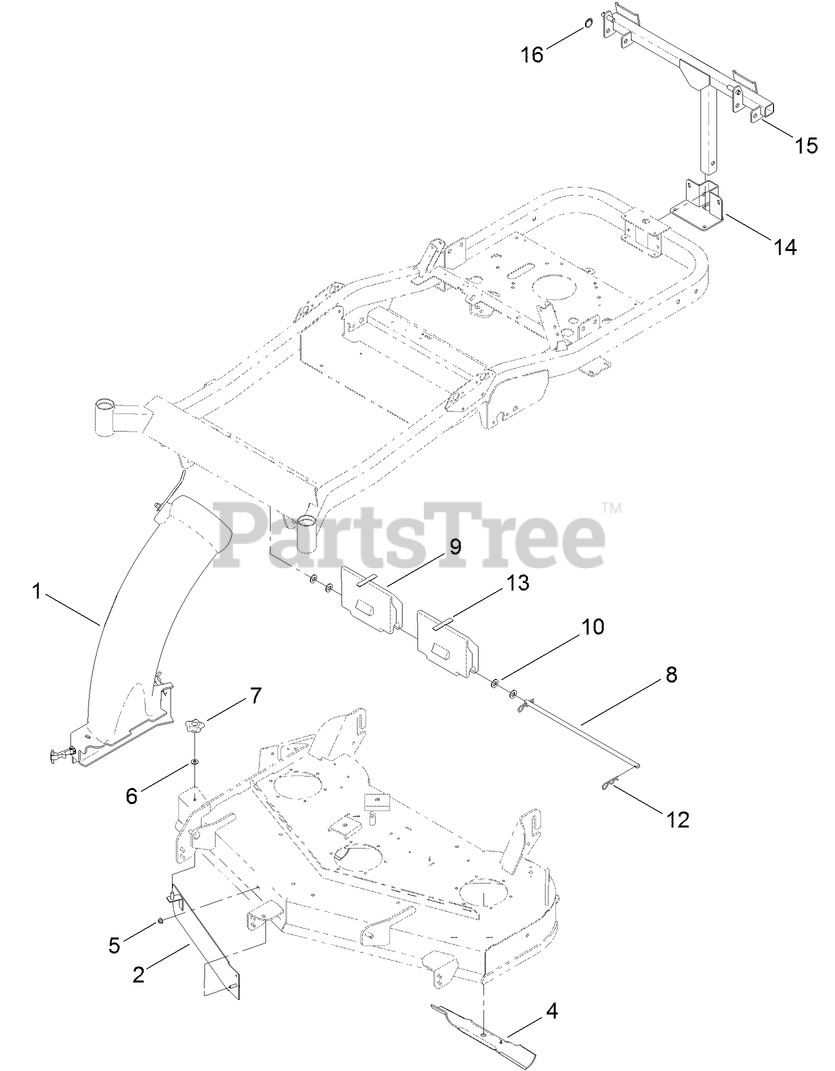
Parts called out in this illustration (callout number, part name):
1	CHUTE ASM
4	BLADE-HI LIFT, 16.50 IN
5	NUT-HF, NI
6	WASHER-FLAT
7	KNOB-LOCKING
8	ROD-DECK, PIVOT
9	WEIGHT-BAGGER
10	WASHER-FLAT
12	PIN-HAIR
13	BUMPER-PAD
14	SUPPORT-BAGGER
15	FRAME-PIVOT
16	PIN-COTTER, CIRCULAR
